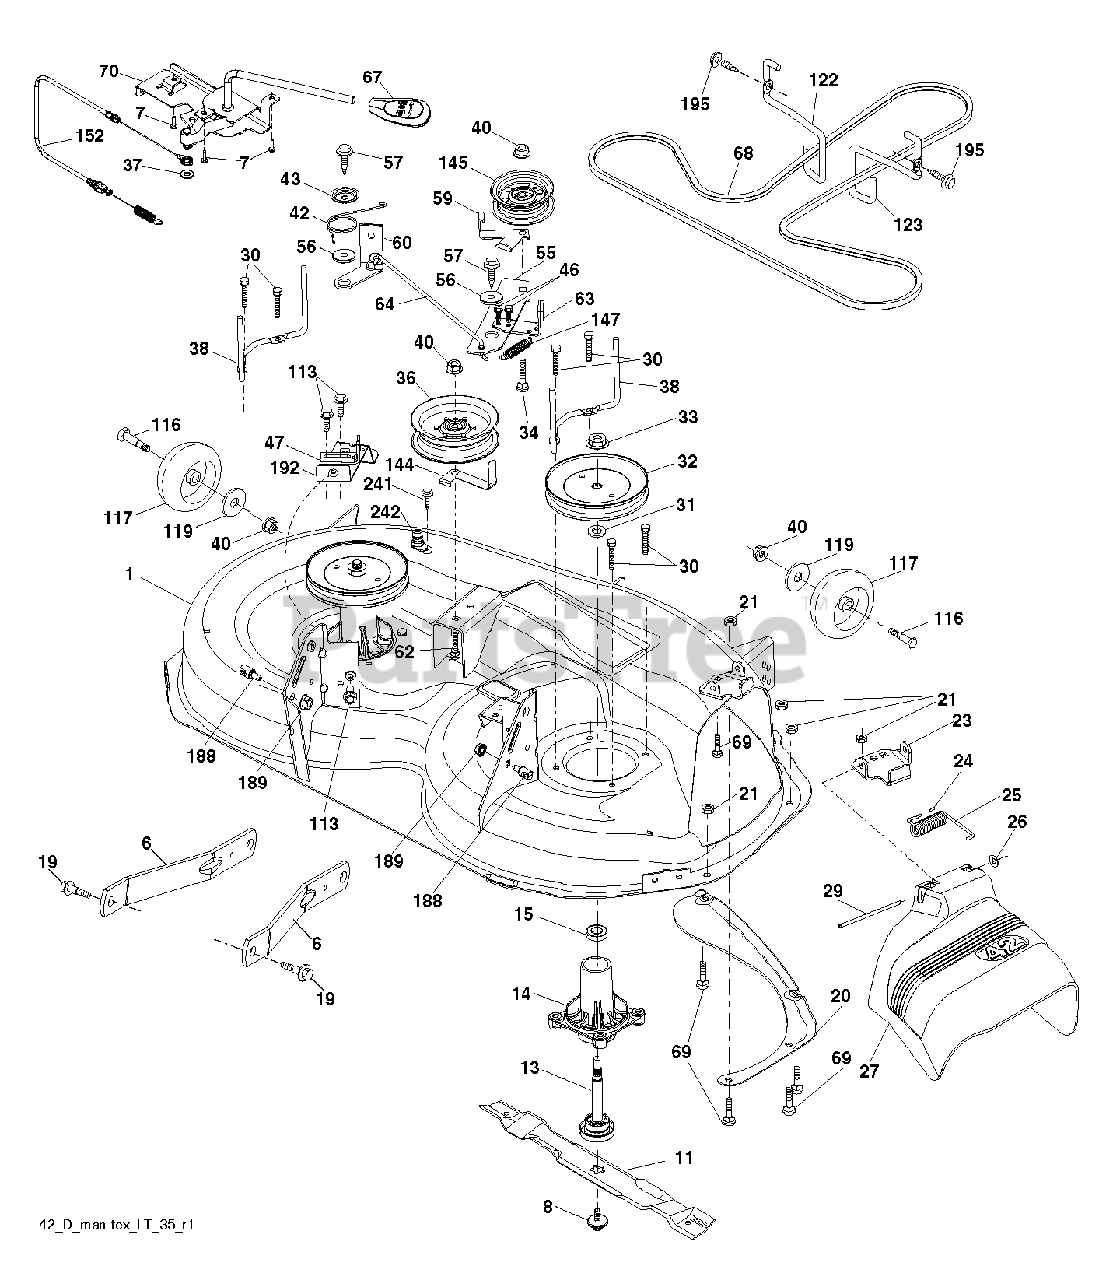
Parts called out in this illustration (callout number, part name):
1	DECK.WELDMNT.42"GREYMS498
6	ARM.SUSPENSION.MOWER.R
7	SCREW.#10 X 0.750.BOS
8	BOLT.WASHER.ASM.7/16-2
11	42" HI-LIFT BLADE
13	SHAFT.ASM.MDRL.N/GREASE.38
14	HOUSING.MANDREL.4PT.
19	BOLT.SHOULDER
20	BAFFLE.VORTEX
21	LOCKNUT
23	BRKT.DEFLECTOR.38"2005+
24	CAP-SLEEVE LT
25	SPRING.TORSION.DEFLECT
26	NUT PUSH M
27	SHIELD.DEFLECTOR.MOWER.42"BLAC
29	ROD.HINGE
30	SCREW, WASHER HEAD
31	WASHER.SPACER.MANDREL
32	PULLEY.MANDREL.5.438.PD
33	NUT.FLANGE.LOCK.TOP
34	BOLT.3/8-16X1.50
36	PULLEY.IDLER.2006
37	WASHER
38	KEEPER.BELT.MANDREL.PULLEY
40	NUT LOCK FLG 3/8-16 UNC
42	SPRING.TORSION.BRAKE
43	SRPING.TORSION.RETAINE
46	SCREW.1/4-20X5/8
47	BRKT.CLUTCH.CABLE
55	IDLER.ARM.42"
56	SPACER.RETAINER
57	SCREW 3/8-16X1
59	GUARD, BELT
60	ARM BRAKE MOWER
63	ARM BRAKE MOWER
64	LINKAGE.BRAKE.ASM.ZINC
67	HANDLE.CLUTCH.CABLE.LT
68	BELT.DECK.DRIVE.42"
69	BOLT
70	CLUTCH.ASM.MANUAL.LT.PRED
113	BOLT.5/16HEX.WHS.HD
116	BOLT M
117	WHEEL.GAGE.HALF.SPOKED
119	WASHER
122	KEEPER BELT ENGINE LH
123	KEEPER BELT RH
144	KEEPER.BELT.MOWER
145	PULLEY.IDLER.48"PRIMARY
147	RETURN SPRING
152	CABLE.MECHANICAL.CLUTCH
188	STUD.FASTNER.W/ANTI-ROTATE
189	NUT LOCK HEX FLANGE 5/16-18
192	BRKT.BRAKE.STAND.LH.
195	SCREW, 3/8-16X3/4
241	SCREW.TT.#10-32X.5.3/8.FLANGE
242	PORT.WASHOUT
